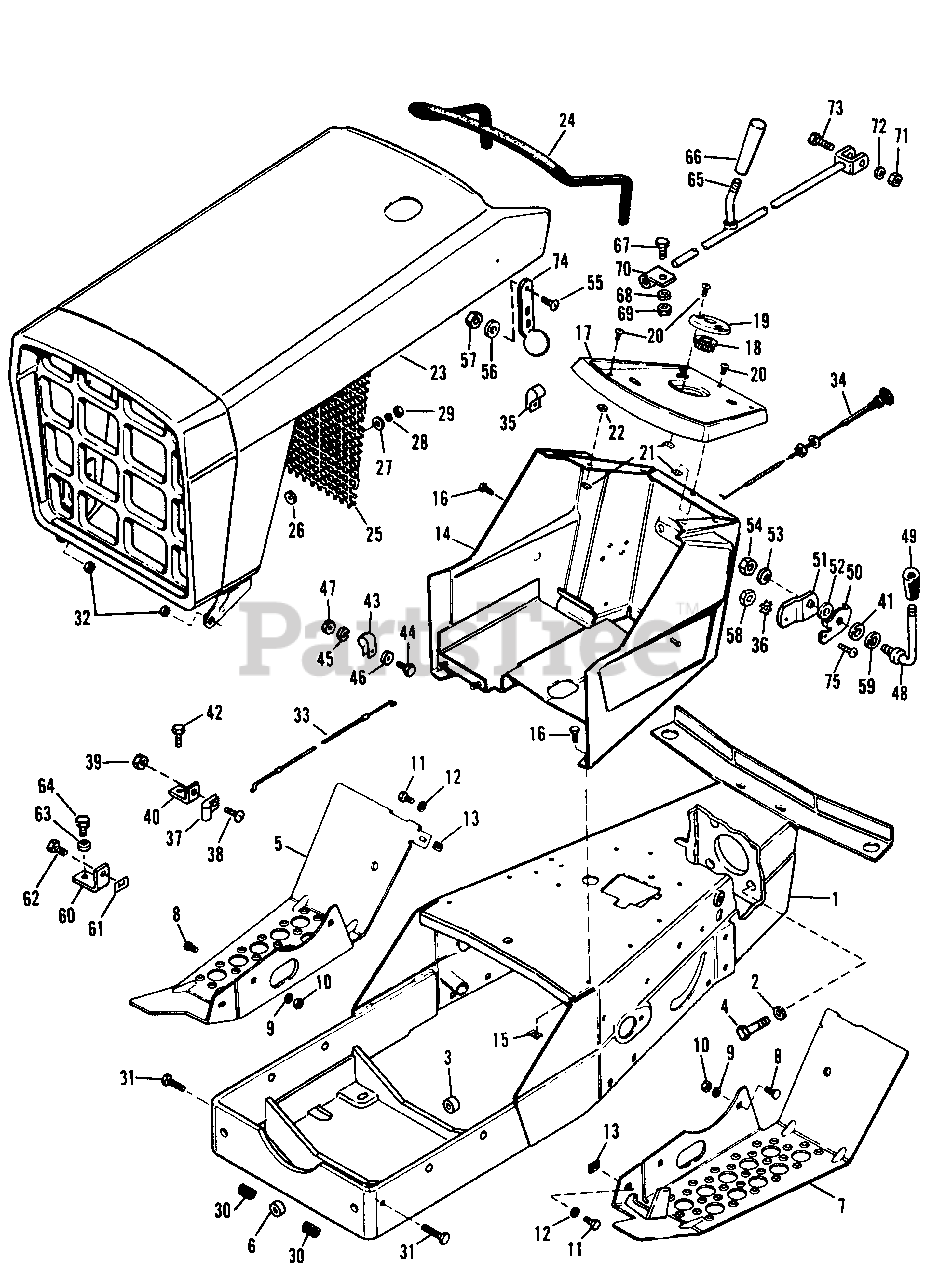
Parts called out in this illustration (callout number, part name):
1	FRAME ASSEMBLY
2	LOCKWASHER, 7/16"
4	CAPSCREW, Hex, 7/16"-14 x 1-1/2" lg.
5	FOOT REST, R.H.
7	FOOT REST, L.H.
8	BOLT, Carriage 5/16"-18 x 3/4" lg.
9	LOCKWASHER, 5/16"
10	NUT, Hex, Full, 5/16"-18
11	CAPSCREW Hex, 5/16-18 x 3/4" lg.
12	LOCKWASHER, 5/16"
13	NUT, Tinnerman
14	DASH ASSEMBLY
15	NUT, Tinnerman
16	SCREW, Self Tapping #14 x 3/4" lg.
17	PANEL, Instrument
18	BUSHING, Steering
19	PLATE, Steering
20	SCREW, Phillips, 1/4"-20 x 1/2" lg.
21	NUT, Tinnerman
22	WASHER, Plain, 3/16"
23	HOOD & GRILLE ASSEMBLY
24	MOLDING, Hood
25	SCREEN, Grille
28	LOCKWASHER, Shake Shakeproof #10
29	NUT, Hex, Full, #10-24
31	CAPSCREW, Hex, 3/8"-16 x 1-1/2" lg.
32	NUT, Hex, Full, Lock, 3/8"-16
33	CONTROL, Throttle
34	CONTROL, Choke
35	CLIP, Bowden, Wire
36	LOCKWASHER, Shakeproof #10
37	CLIP, Bowden, Wire
38	SCREW, Rd. Hd., #10-30 x 3/8" lg.
39	NUT, Hex, Full, #10-32
40	BRACKET, Throttle
42	SCREW, Self Tapping, 1/4"-20 x 5/8" lg.
44	CAPSCREW, Hex, 1/4"-20 x 5/8" lg.
45	LOCKWASHER, 1/4"
46	WASHER, Plain, 1/4"
47	NUT, Hex, Full, 1/4"-20
48	HANDLE, Clutch
49	KNOB
50	STOP, Throttle
51	ATM, Throttle
53	WASHER, Dish Type
54	NUT, Hex, Full, Lock, 3/8"-16
55	SCREW, Phillips Hd. #10-32 x 1/2" lg.
57	NUT, Center Lock, #10-32
58	NUT, Hex, Full, #10-32
60	BRACKET, Pulley Guard
61	NUT, Tinnerman
62	CAPSCREW, Hex, 1/4"-20 x 3/4" lg.
63	WASHER, Plain, 3/16"
64	CAPSCREW, #14 x 1-1/4 "lg
65	ROD ASSEMBLY, Shifter
67	CAPSCREW, Hex, 5/16"-18 x 1-1/2" lg.
68	LOCKWASHER, 5/16"
69	NUT, Hex, Full, 5/16-18
70	GUIDE ASSEMBLY, Shift Rod
71	NUT, Hex, Full, 1/4"-20
72	LOCKWASHER, 1/4"
73	CAPSCREW, Hex, 1/4"-20 x 5/8" lg.
74	STRAP, Hood
75	SCREW, Rd. Hd. #10-32 x 1/2" lg.
